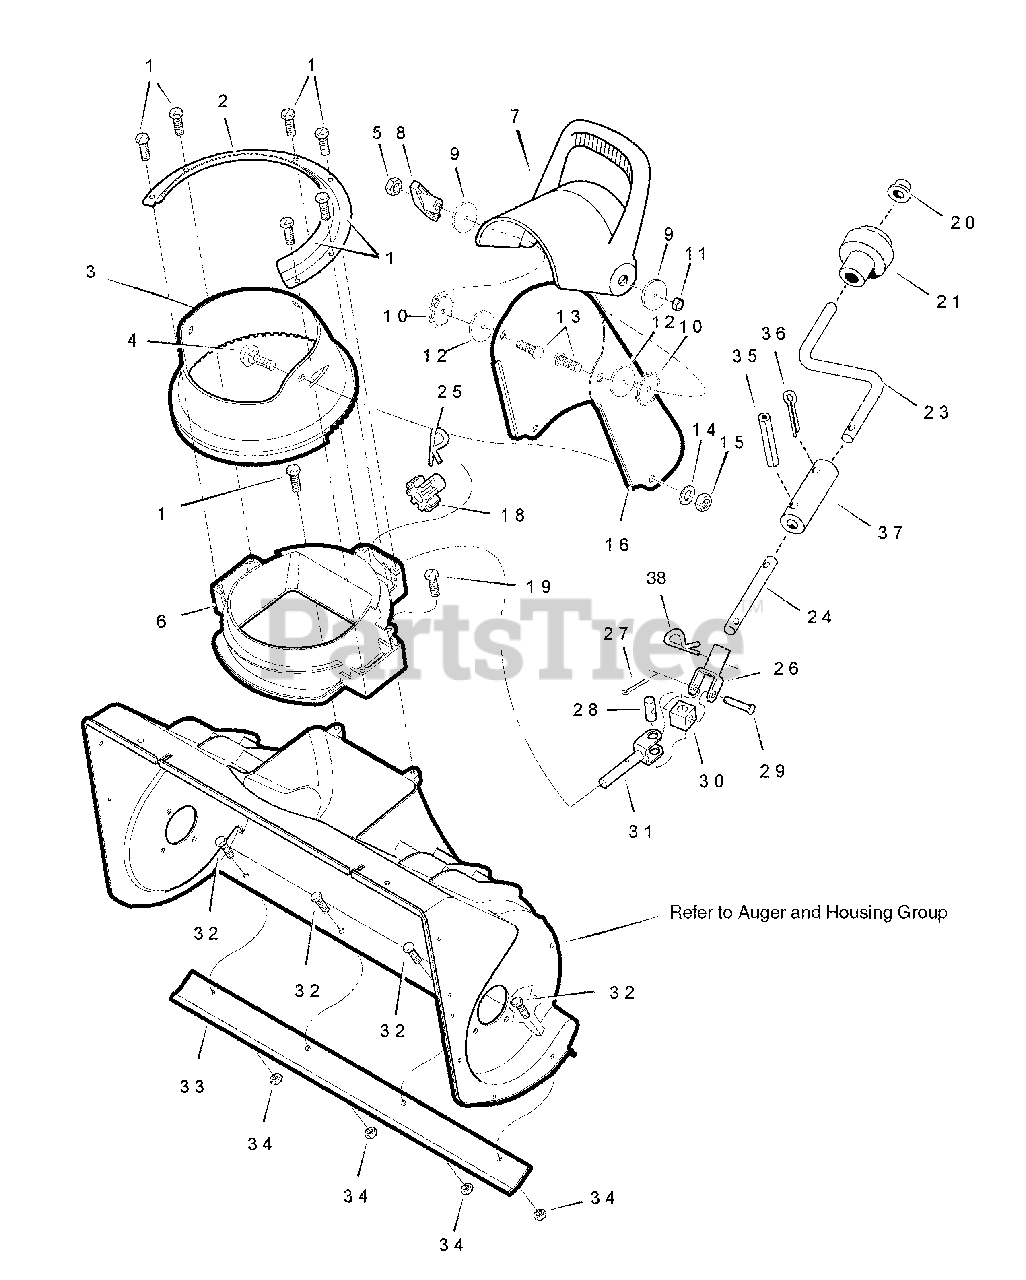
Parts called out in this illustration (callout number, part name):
1	SCREW, 1/4-14
2	RETAINER, Chute Ring
3	RING, Chute
4	BOLT, Carriage 5/16-18 x 3/4
5	NUT, 5/16-18 Reghex
6	NECK, Chute
7	CHUTE, 22" Upper
8	T-KNOB, 3.00 Plastic
9	WASHER, Flat 1 - 1/2 O.D
10	LOCKWASHER, Shakeproof
11	LOCKNUT, Hex 5/16-18
12	WASHER, Rubber 1-1/2 O.D
13	BOLT, Upper Chute
14	WASHER, Flat 13/32 x 13/16
15	NUT, 5/16-18 Hex, Nylock
16	CHUTE, Lower
18	GEAR, 9-Tooth
19	SCREW, 1/4-14 x .75
20	NUT, Push
21	KNOB, Crank
23	CRANK, Chute Rotation
24	HANDLE, Chute Rotator Lower
25	PIN, Hair
26	YOKE ASSEMBLY, Adapter
27	PIN, Cotter
28	PIN, Universal Joint
29	PIN, Clevis
30	BLOCK, Universal Pivot
31	ROD, Lower Crank
32	SCREW 1/4-20 x 3/4
33	BLADE, Scraper
34	LOCKNUT, Hex 1/4-20
35	PIN, Spring 5/32 x 1.00
36	CLIP, Hairpin 3/32 x 1.625 Black
37	CHUTE HANDLES, Spliced
38	Pin, Cotter
